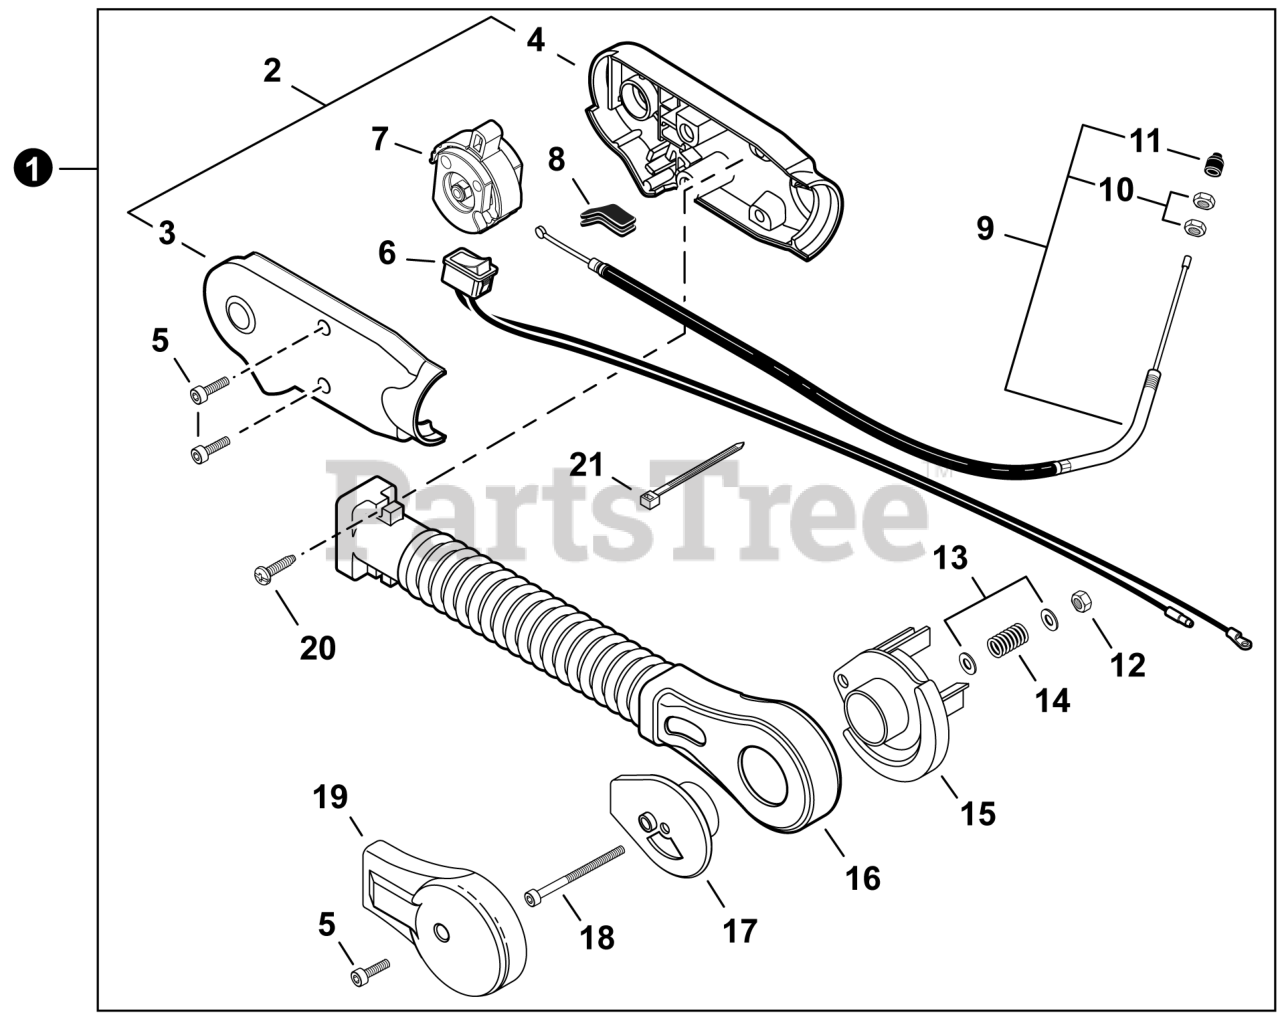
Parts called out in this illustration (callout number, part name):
1	THROTTLE CONTROL KIT - HIP MOUNT
2	GRIP SET, THROTTLE
3	GRIP, LEFT THROTTLE
4	GRIP, RIGHT THROTTLE
5	BOLT 5x14
6	SWITCH, ON-OFF
7	CONTROL, THROTTLE
8	GROMMET
9	CABLE ASSY, THROTTLE
10	NUT 6 MM
11	CAP, DUST
12	NUT, LOCK M5
13	WASHER 5.5x18x1
14	SPRING, COMPRESSION 9.53x24.13
15	BRACKET, ARM - INNER
16	ARM, THROTTLE CONTROL
17	BRACKET, ARM - OUTER
18	SCREW M5x80
19	BRACKET, ARM - OUTER
21	STRAP, CABLE
